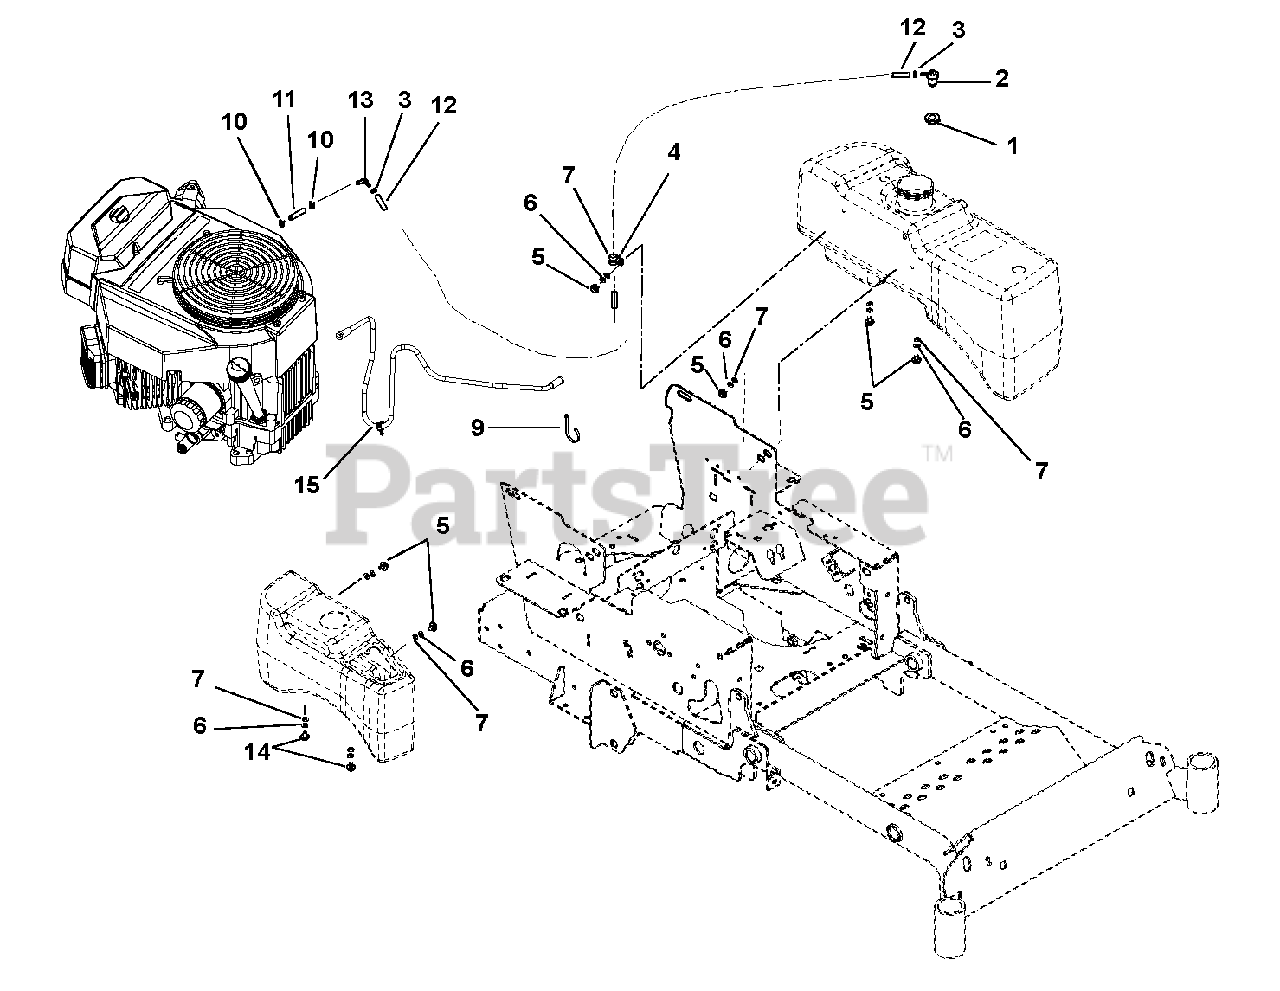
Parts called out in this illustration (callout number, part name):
2	Valve
3	Hose, Clamp (Serial No. 020000 – 024999)
4	Clamp (Serial No. 020000 – 024999)
5	Bolt, .31-18 x .62
6	Washer, Locking .31 x .078 Regular
7	Washer, Flat Steel .38 x .875 x .083
8	Cupholder, Snap-in 3.75 O.D.
9	Tie, Cable LG 5.50
10	Clamp, Spring .188 (Serial No. 020000 – 024999)
11	Hose, Fuel .18" (Serial No. 020000 – 024999)
12	Hose, Fuel .25" (Serial No. 020000 – 024999)
13	Fitting, 90° Vacuum .18 x .25 (Serial No. 020000 – 024999)
14	Screw, Plastite .25-10 x .75 YZ
15	Kawasaki, Line HD (Serial No. 025000 +)
